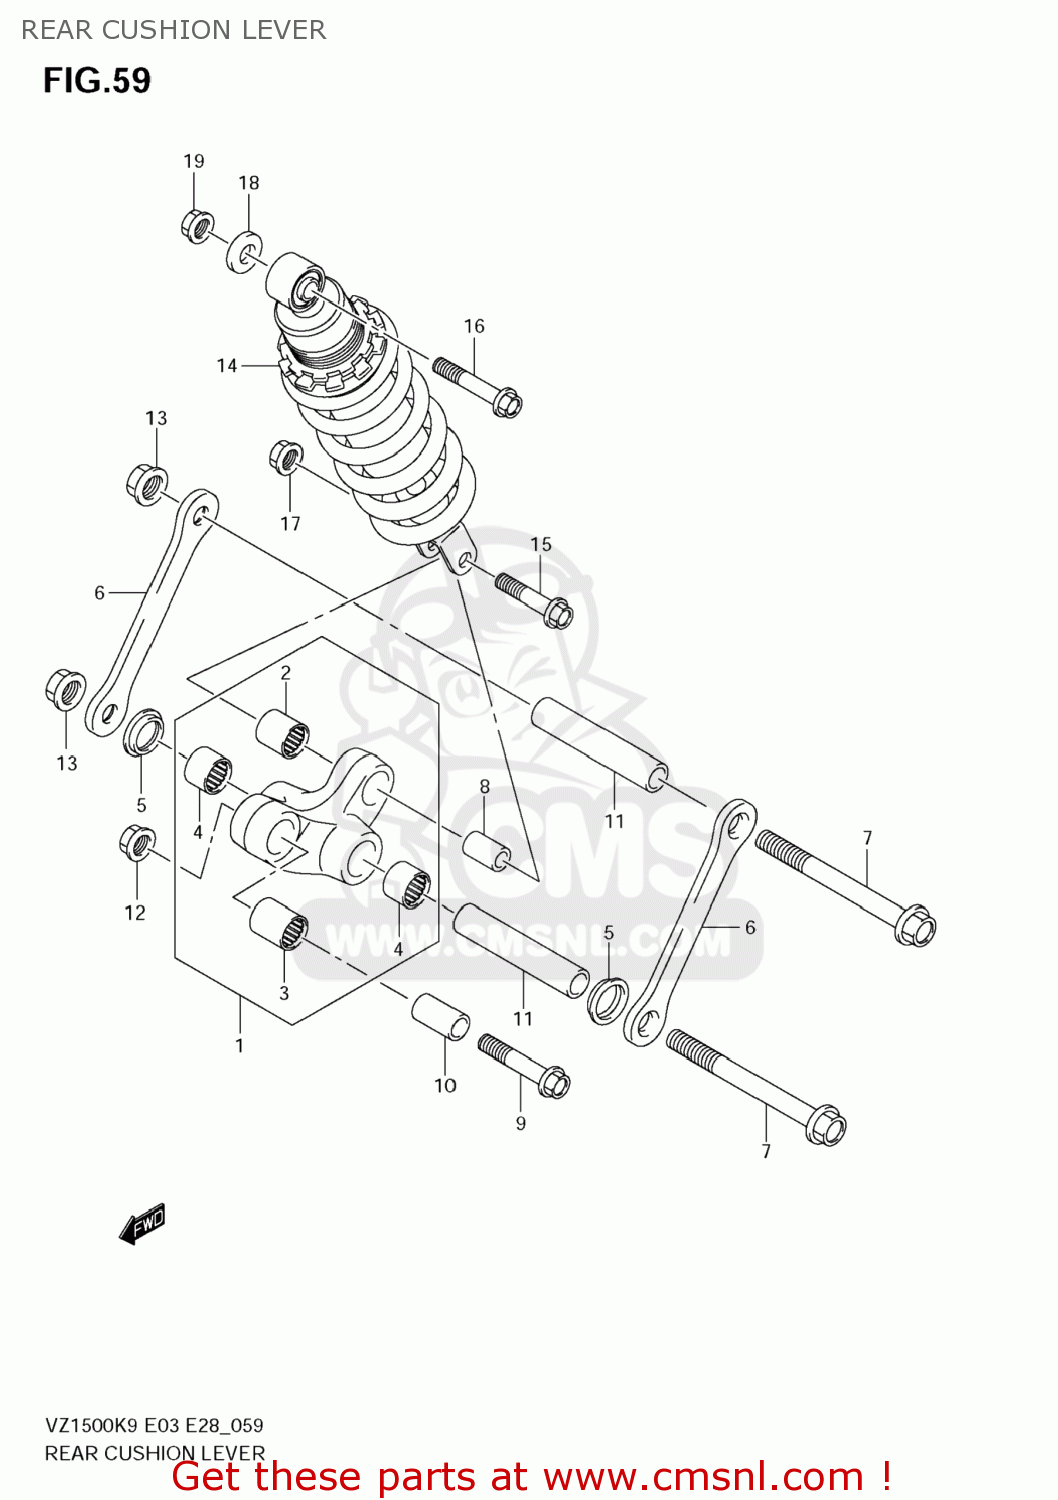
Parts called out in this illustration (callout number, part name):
1	LEVER SET,RR CUSHION
2	BEARING(20X27X26)
3	BEARING(20X27X32)
4	BEARING(22X28X20)
5	SEAL,SWINGING ARM RR
6	ROD,RR CUSHION
7	BOLT,RR CUSHION LEVER UPR
8	SPACER,RR CUSHION LEVER FR
9	BOLT(14X66)
10	SPACER(14X20X34)
11	SPACER(16X22X105)
12	NUT
13	NUT
14	ABSORBER ASSY,RR SHOCK
15	BOLT,CUSHION LEVER FR
16	BOLT,RR CUSHION LEVER FR
17	NUT
18	SPACER(12.1X25X14.5)
19	NUT
